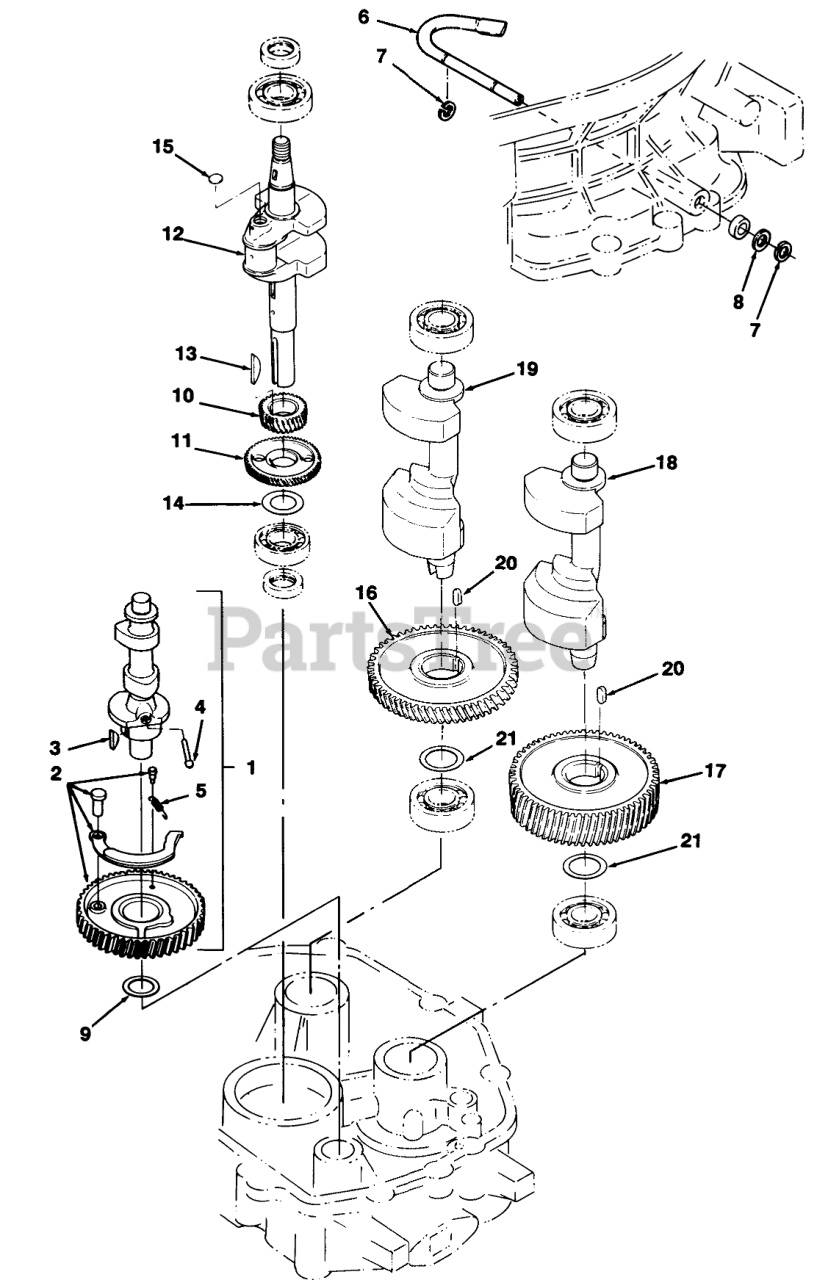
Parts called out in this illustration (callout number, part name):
1	Camshaft Assembly (Incl. Ref. #2-5)
2	CAMGEAR ASS'Y
3	KEY-CAMGEAR
4	PIN-DECOMPRESSION
5	SPRING-DECOMPRESSION
6	SHAFT-GOVERNOR LEVER
7	CLIP-RETAINER
8	WASHER-FLAT
9	SHIM-CAMSHFT 0.5MM
10	GEAR-CRANKSHAFT
11	GEAR-BALANCER
12	Crankshaft
13	KEY-CRANKSHAFT GEAR
14	SHIM-CRANKSHFT 0.2MM
15	PLUG-EXPANSION
16	GEAR-BALANCER
17	GEAR-BALANCER
18	SHAFT-BALANCER
19	SHAFT-BALANCER
20	KEY-BALANCER GEAR
21	SHIM-BAL SHAFT 0.5MM
